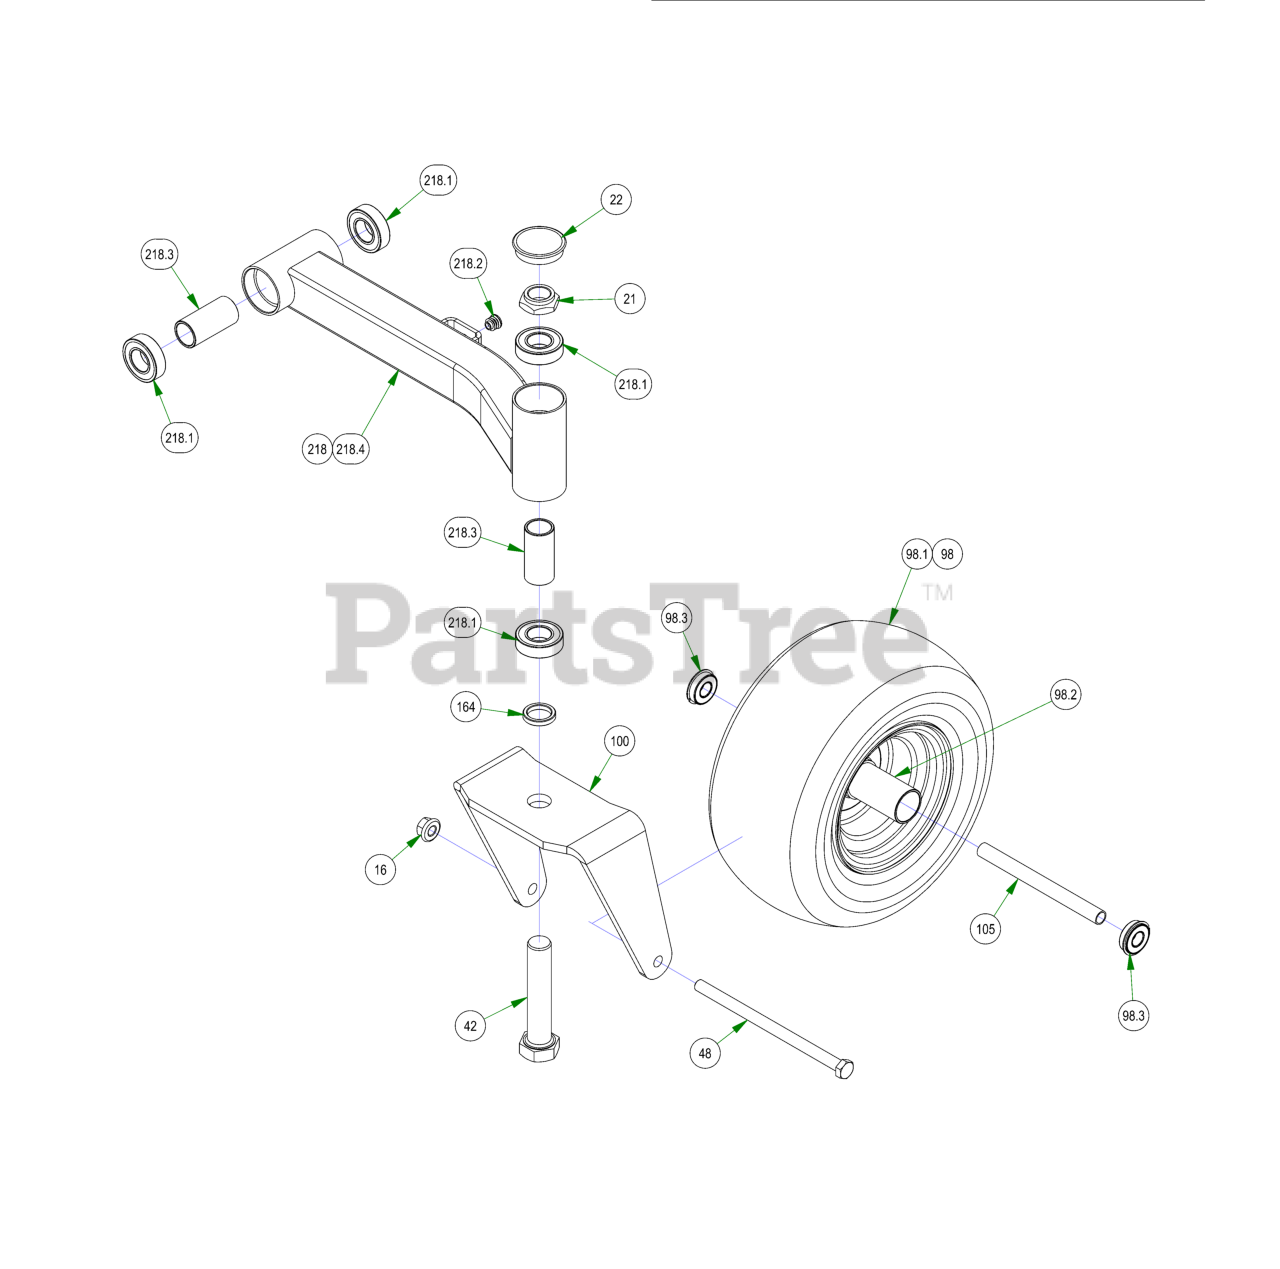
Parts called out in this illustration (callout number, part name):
16	1/2-13 NYLON INSERT FLANGE LOCKNUT ZINC
21	1"-14 NYLON INSERT JAM LOCKNUT ZINC
22	2017 Bearing Cover
42	1"-14 X 5 HEX CAP SCREW (GR.8) ZINC YELLOW
48	1/2-13 X 8-1/2 HEX CAP SCREW (GR.5) ZINC
98	13x6.5-6 Black Tire and Wheel Assembly
98.1	13 x 6.50 - 6 Tire
98.2	Front Tire Rim
98.3	Ball Bearing w/Retainer, 99502H-NR, .625 Bore x 1.375 OD x .4375 Width
100	2017 ZT Front Fork
105	Front Wheel Spanner
164	Spacer, 1x1.375x.25
218	2021 ZT Suspension Arm Assembly Left (48", 54", & 60")
218.1	1641 BEARING W/2 CONTACT RUBBER SEALS
218.2	5/8 Round Insert
218.3	2016 Front Bearing Spacer
218.4	2021 ZT LH Front Arm
